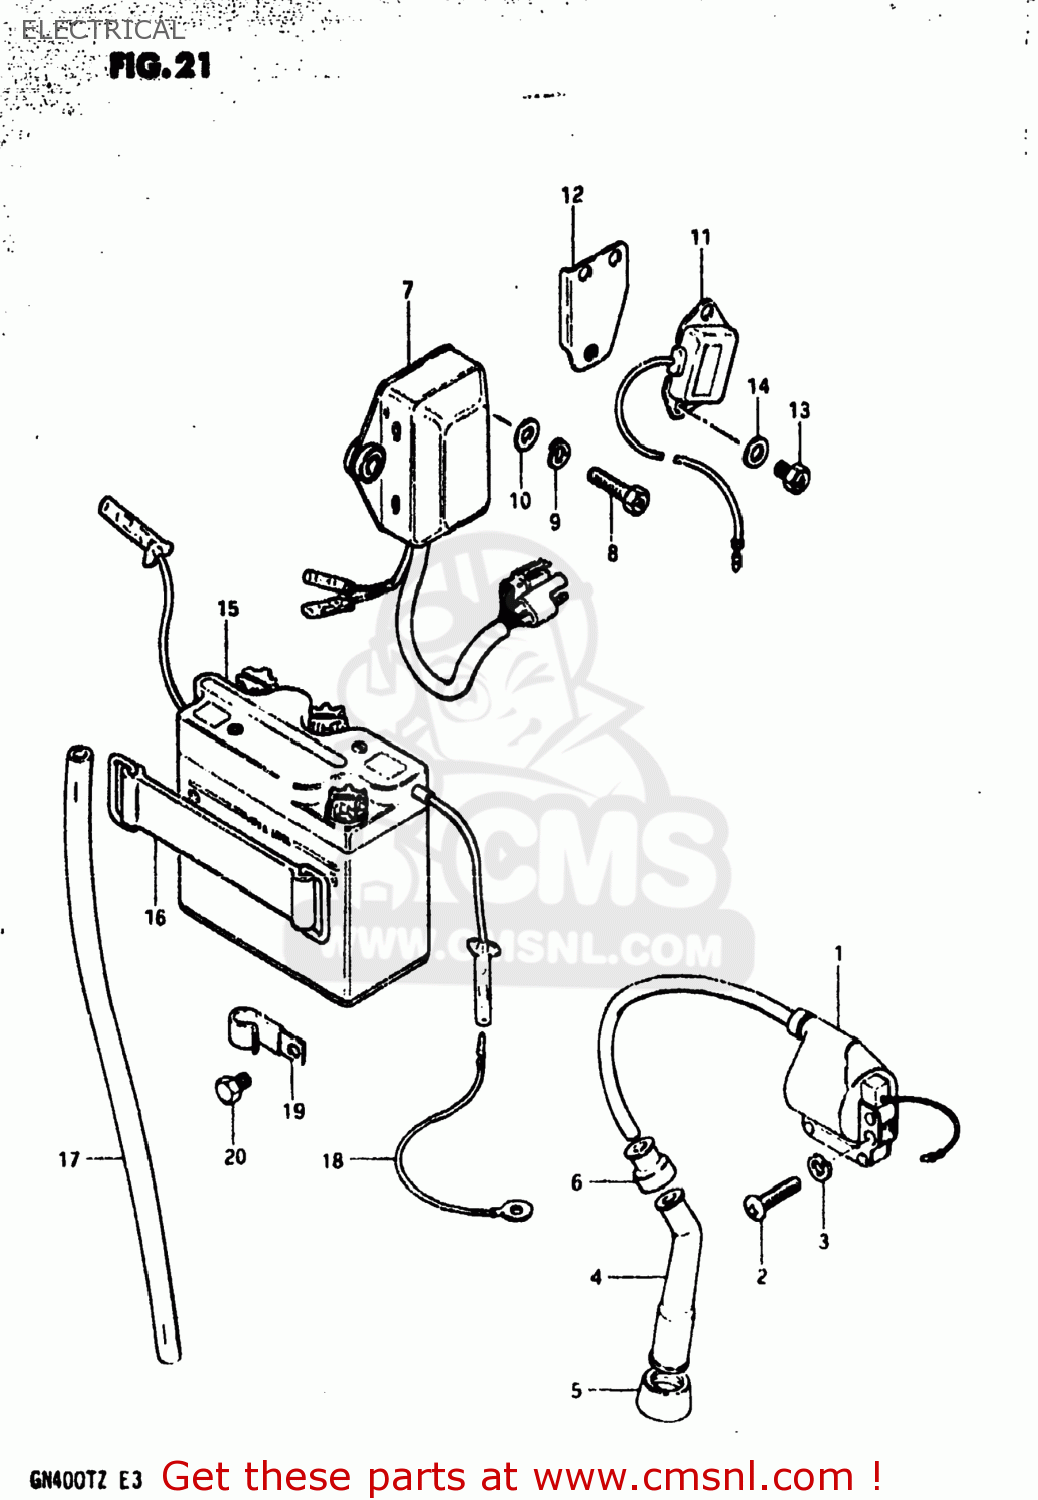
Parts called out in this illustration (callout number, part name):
1	COIL ASSEMBLY,IGNITION
2	SCREW
3	LOCK WASHER
4	CAP ASSY,SPARK PLUG
5	SEAL,SPARK PLUG
6	SEAL,SPARK PLU
7	CDI UNIT
8	BOLT(6X20)
9	LOCK WASHER
10	WASHER
11	REGULATOR ASSEMBLY,VOLTAGE
12	PLATE,REGULATOR
13	SCREW(6X10)
14	WASHER
15	BATTERY ASSEMBLY
16	BAND
17	HOSE,BATTERY EXHAUST
18	LEAD WIRE
19	CLAMP
20	BOLT
